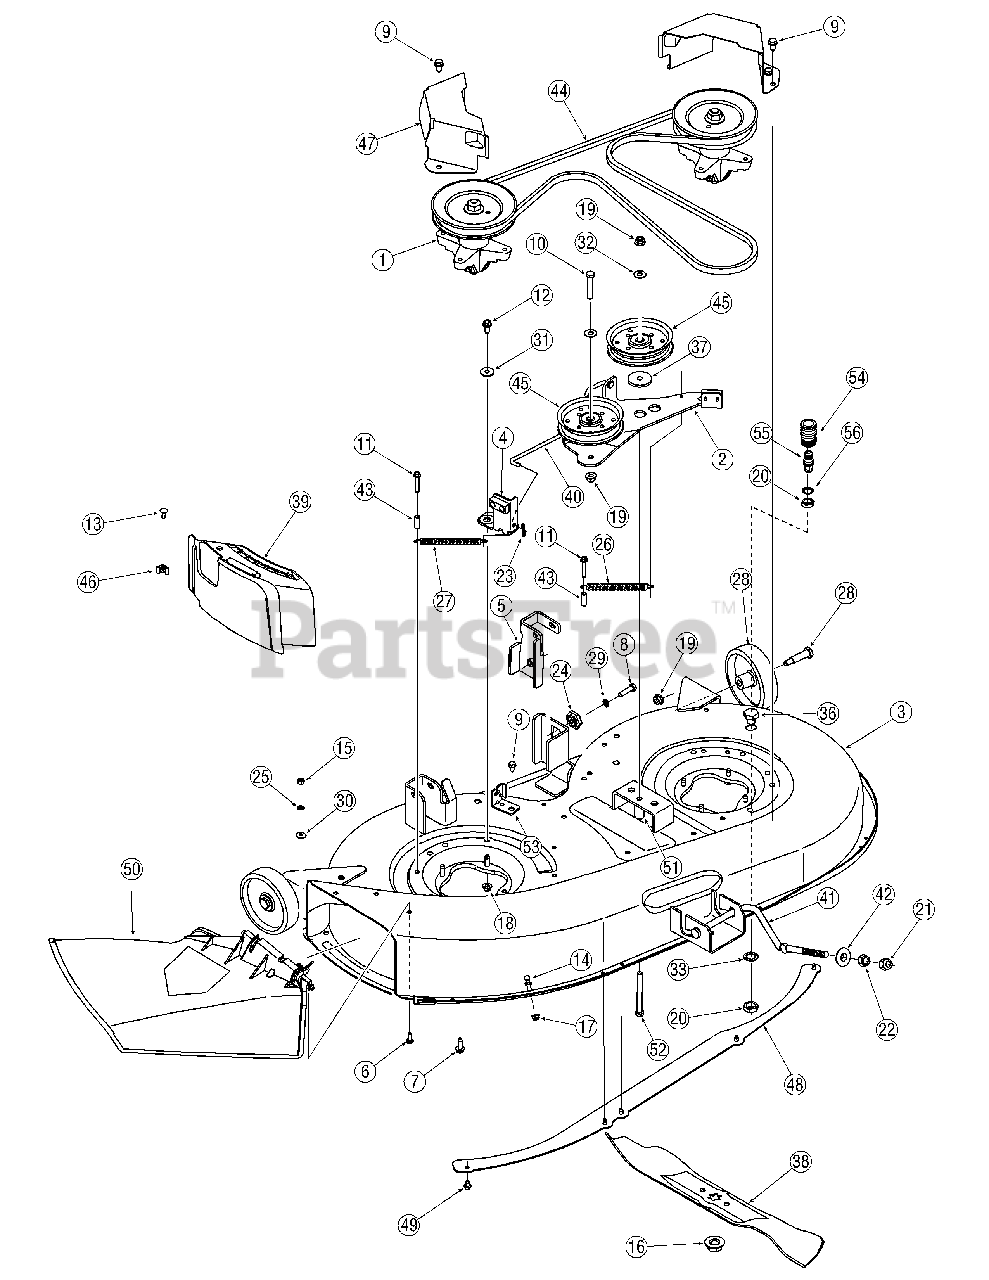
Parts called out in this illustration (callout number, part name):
1	Spindle Assembly, Pul, 6.23" Dia
3	Deck Shell, 42" (w/o Wheel Brackets)
6	Screw, 1/4-20, .750, Gr5
7	Screw, 5/16-18, 0.875
8	Screw, 5/16-18, 1.250
9	Screw, 5/16-18, 0.625
10	Screw, 3/8-16, 1.75, Gr5
11	Screw, 1/4-20, 1.500
12	Screw, 5/16-18, .75, Gr5
13	Carriage Screw, , 1/4-20 x .62
14	Pin, Grasscatcher, 1/4-20
15	Nut, Hex, 1/4-20, Gr5
16	Nut, Flange, 5/8-18
17	Nut, Flange Lock, 1/4-20, GrF, Nylon
18	Nut, Flange Lock, 5/16-18, GrF, Nylon
19	Nut, Flange Lock, 3/8-16, GrF, Nylon
20	Nut, Hex, M16-1.5
21	Nut, Hex Lock, 1/2-13, Gr8, Nylon
22	Nut, Hex, 1/2-13, Gr5
23	Pin, Cot, .072 Dia. x 1.13
24	Gear, Deck Adjustment
25	Nut, Push, .25 ID x .50 OD
26	Spring, Extension, .75 Dia. x 6.375
27	Spring, Extension, .50 Dia. x 6.375
28	Wheel, Deck 5.0 x 1.38
29	Washer, Lock, 5/16
30	Washer, Bell, .265 x.75 x .062
31	Shoulder Spacer.8840 x .190
32	Washer, Flat, .385 x .87 x .06
33	Washer, Lock, 5/8, Internal Tooth
34	Washer, Flat, .64 x 1.24 x .06
35	Screw, Shoulder, .498 x 1.53, 3/8-16
36	Plug, Screw, M16 x 1.5
37	Spacer, Shoulder, .8540 x .190
38	Blade, 21.23", Star 3-in-1
39	Mulch Plug
40	Control Rod, Brake
41	Deck Rod, Front Adjustable
42	Pivot Cup, Deck Lift
43	Spacer, .260 x .372 x 1.030
44	Belt, V-Type
45	Idler Pulley, 4.25" Dia.
46	Wing Nut, 1/4-20
49	Screw, 1/4-20, .500
50	Chute Assembly, Discharge
51	Spacer, 1.46"
52	Screw, 3/8-16, 3.50, Gr5
54	Water Nozzle Adapter (Optional)
55	Deck Water Nozzle (Optional)
56	Lock Washer (Optional)
